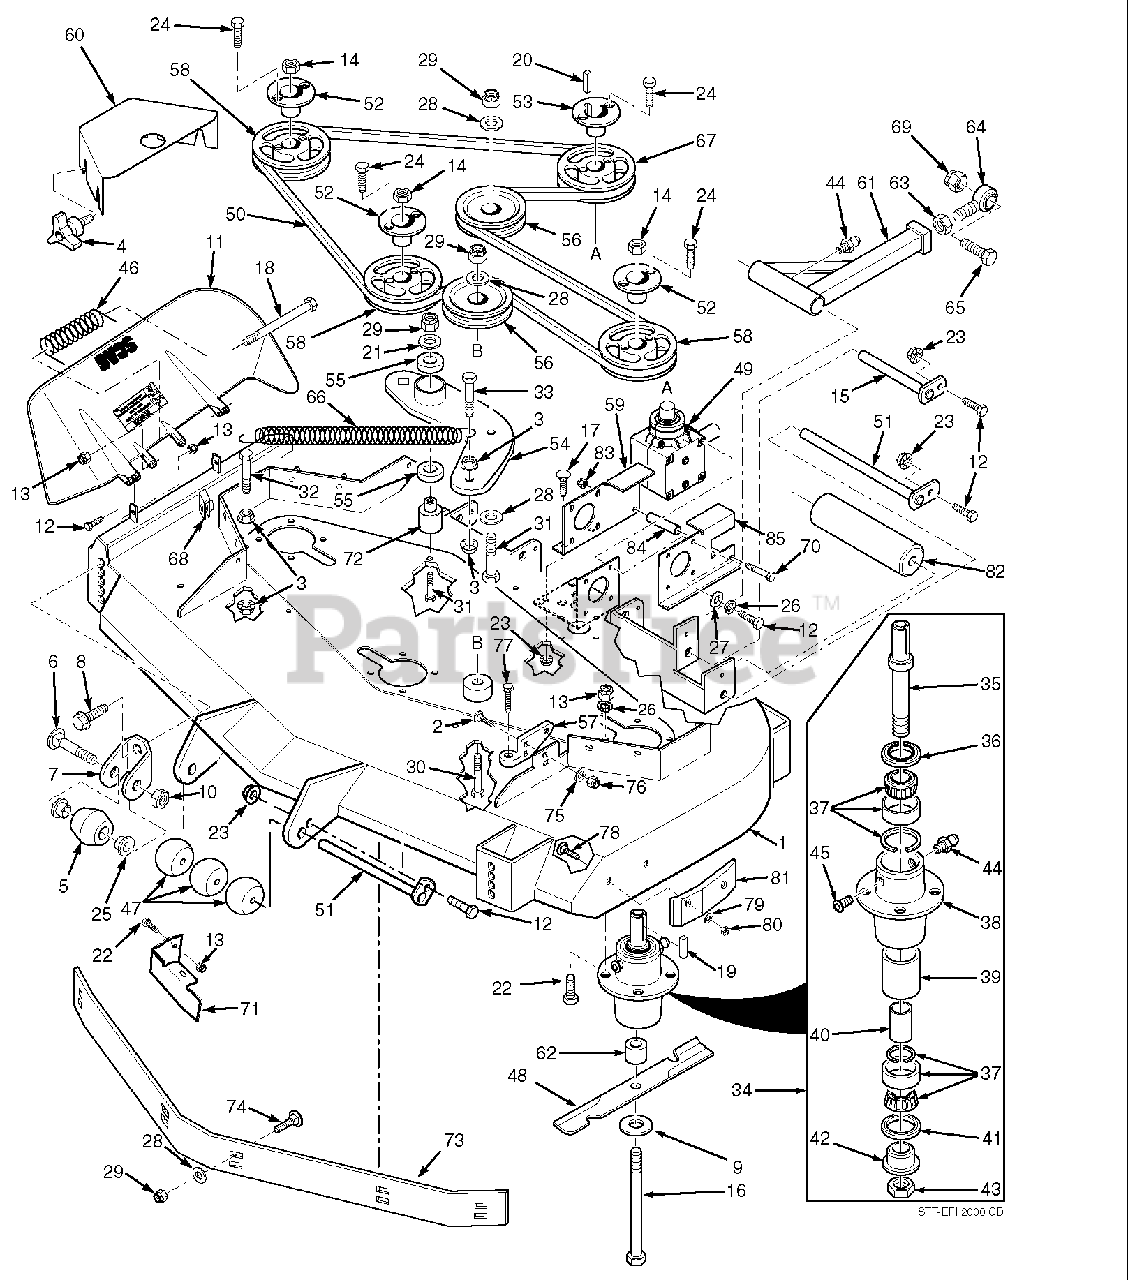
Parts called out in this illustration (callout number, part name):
1	Cutter Deck Velocity Plus
2	Bolt, Carriage 7/16-14 x 1-1/4"
3	Nut, Hex Serr. Flng. 3/8-16
4	Wing Nut, 3/8-16
5	Anti-Scalp Wheel
6	Bolt, Carriage 3/8-16 x 4"
7	Anti-Scalp Wheel Bracket
8	Bolt, Hex Serr. Flng. 3/8-16 x 1"
9	Flatwasher, 5/8" Hardened
10	Locknut, 3/8-16 Center Lock
11	Discharge Chute
12	Bolt, Hex Hd. 5/16-18 x 1-1/2" - Rear
13	Nut, Hex Elastic Stop 5/16-18 Grd. 8
14	Nut, 5/8-11 UNC
15	Pusharm Shaft
16	Bolt, Hex Hd. 5/8-11 x 9-1/2"
17	Bolt, Carriage 5/16-18 x 3/4"
18	Bolt, Hex Hd. 5/16-18 x 4-1/2"
19	Key, 1/4 x 1/4 x 2"
20	Key, 1/4 x 1/4 x 1-1/4"
21	Flatwasher,3/8 (.39 x .938 x .105") HD
22	Bolt, Hex Hd. 5/16-18 x 1-3/4"
23	Nut, Hex Serr. Flng. 5/16-18
24	Bolt, Hex Hd. 1/4-20 x 1" Grd. 8
25	Bushing, .376" I.D. Oilite
26	Lockwasher, 5/16"
27	Flatwasher, 5/16" (.375 x .875 x .083")
28	Flatwasher, 3/8" (.391 x .938 x .105")
29	Nut, Hex Elastic Stop 3/8-16
30	Bolt, Hex Hd. 3/8-16 x 3-1/4"
31	Bolt, Hex Hd. 3/8-16 x 3"
32	Bolt, Hex Hd. 3/8-16 x 1-1/2"
33	Bolt, Hex Hd. 3/8-16 x 1-1/2" Grd. 8
34	Spindle Assembly
35	Spindle Shaft
36	Seal, Top
37	Bearing Assembly
38	Spindle Housing
39	Spacer, Outside
40	Spacer, Inside
41	Seal, Bottom
42	Spindle Bushing, Bottom
43	Nut, Special 1-1/16-18
44	Grease Fitting
45	Relief Fitting, Tapered Spindle
46	Spring, Discharge Chute
47	Wheel, Anti-Scalp
48	Cutter Blade, 21"
49	Gearbox Assembly, Deck Drive
50	Belt, Cutter Deck Drive
51	Roller Shaft
52	Tapered Hub, 1-1/8" Bore
53	Tapered Hub, 1" Bore
54	Idler Arm, Cutter Deck
55	Bearings, Ball
56	Pulley, Idler
57	Lever Assembly, Deck Level
58	Pulley, 6.35" O.D.
59	Mounting Plate, RH Gearbox
60	Belt, Cover
61	Pusharm
62	Spacer, Spindle Bottom
63	Nut, Hex Hd. 5/8-18 UNF
64	Rod End, 5/8" Male RH Thread
65	Bolt, Hex Hd. 5/8-11 x 4-1/2"
66	Spring, Cutter Deck
67	Pulley, 6.75 O.D.
68	U-Nut, 3/8-16
69	Nut, Hex Elastic Stop 5/8-11
70	Bolt, Hex Hd. 5/16-18 x 4-3/4"
71	Discharge Baffle 61V
72	Pivot, Idler - Short
73	Baffle, Custom Cut 61V
74	Bolt, Carriage 3/8-16 x 1"
75	Flatwasher, 7/16 (.500 x 1.25 x .083")
76	Nut, Elastic Stop 7/16-14
77	Bolt, Deck Adjust
78	Bolt, Carriage 5/16-18 x 3/4"
79	Flatwasher, 5/16"
80	Nut, Center Lock 5/16-18
81	Wear Pad
82	Wheel, Anti-Scalp
83	Nut, Elastic Stop 5/16-18
84	Spacer, Gearbox Mount
85	Mounting Plate, LH Gearbox
